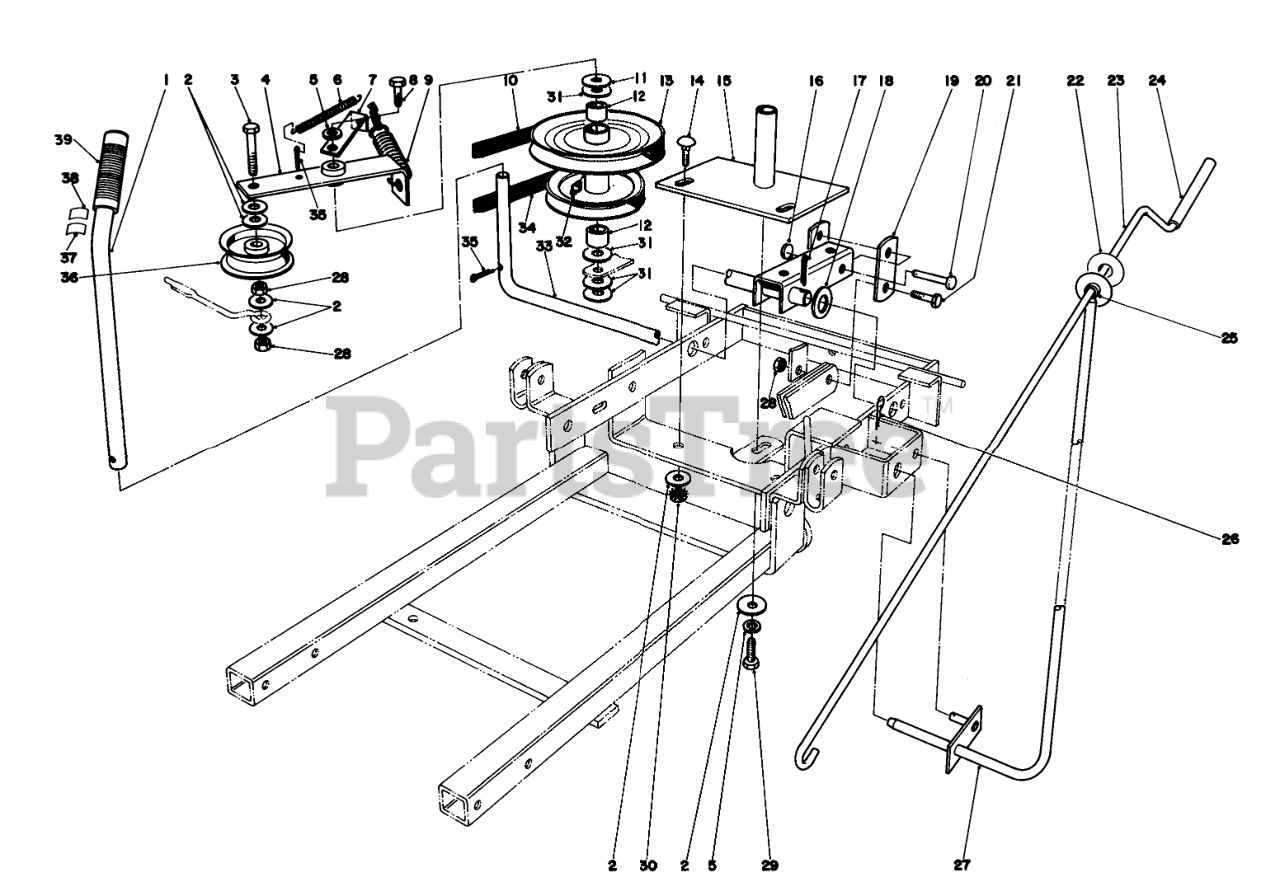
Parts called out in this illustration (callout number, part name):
1	Lift Handle
2	WASHER-FLAT
3	SCREW-HH
4	Idler Arm
5	WASHER-LOCK
6	Spring-Detent
7	Bracket-Spring Anchor
8	SCREW-HH
9	Spring
10	V-BELT
11	Washer
12	Roller Bearings
13	PULLEY HSG WA
14	BOLT-CARR
15	Mounting Bracket-Pulley
16	Spring Clip
17	PIN-COTTER
18	Spacer
19	Strap-Lift Link
20	Pin-Clevis, Handle
21	SCREW-HH
22	Decal-Spout Rotation
23	Rod-Deflector Control
24	Grip-Handle
25	Nylon Bushing
26	PIN-HAIR
27	Crank Rod Support (Incl. Ref. #22 & 25)
28	NUT-LOCK, CONE
29	SCREW-HH
30	NUT-KEPS
31	Washer
32	FITTING-GREASE
33	Lift Bar
34	V-Belt
35	PIN-COTTER
36	IDLER PULLEY ASM
37	Decal-Lift Control
38	Decal-Raise & Lower
39	GRIP-HANDLE
